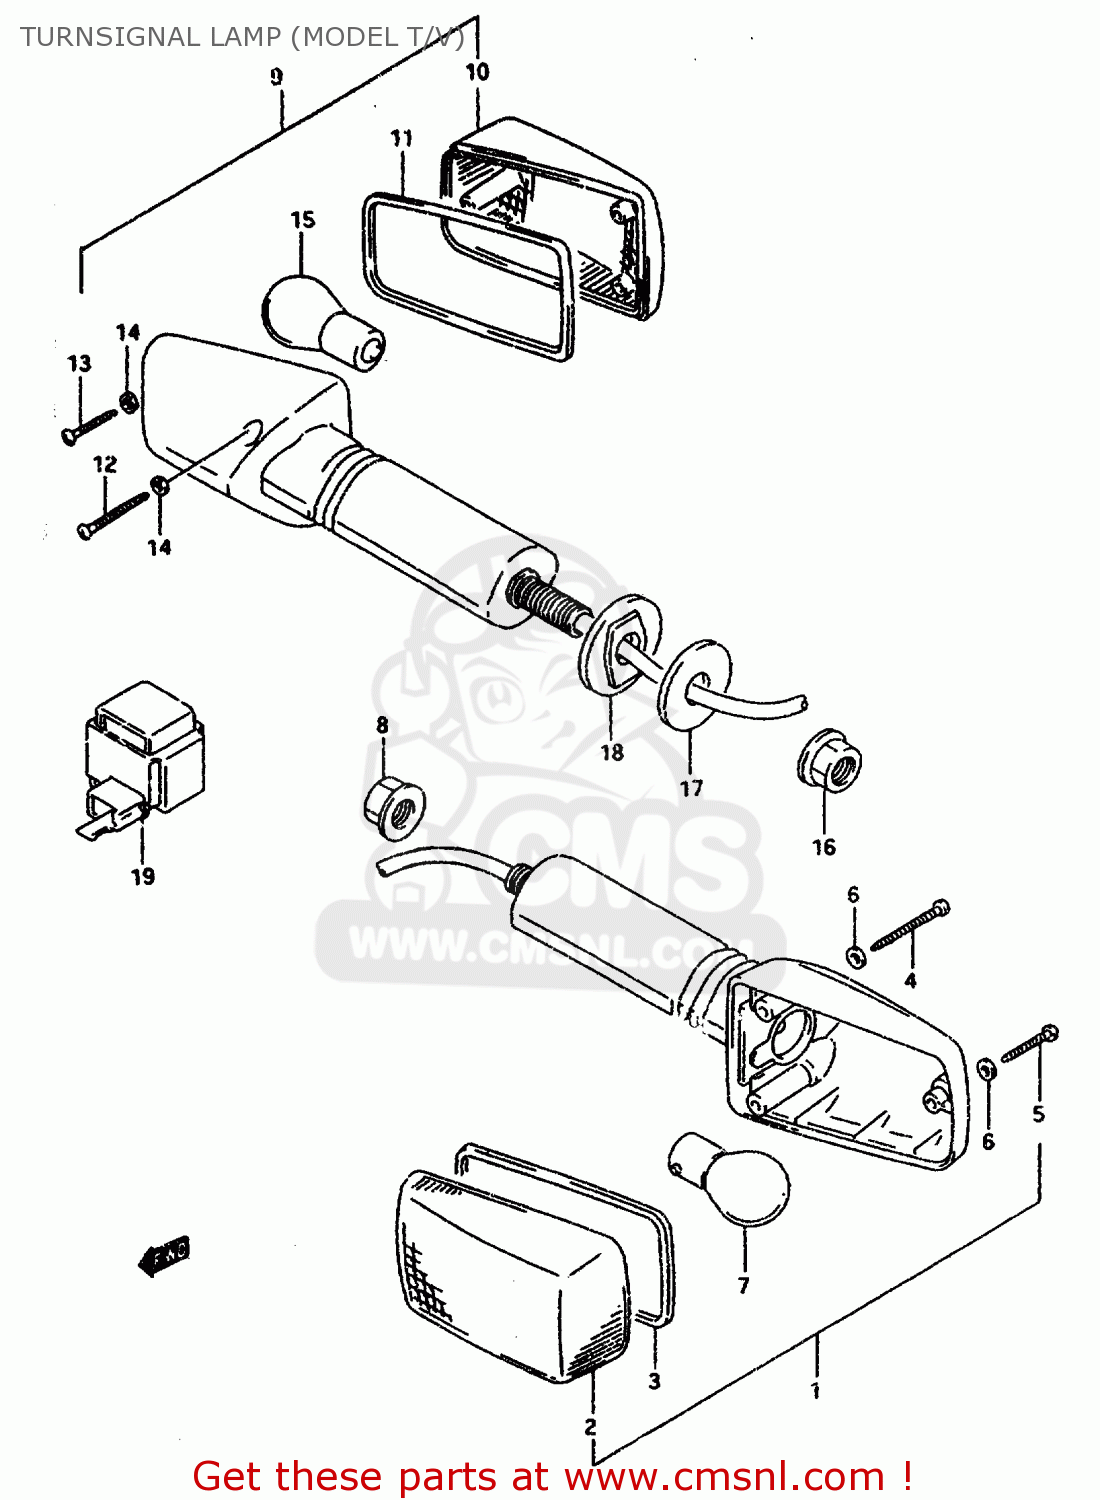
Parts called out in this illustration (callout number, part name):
1	LAMP ASSY,FR TURN SIGNAL
2	LENS
3	GASKET (NAS)
4	SCREW(3X30)
5	SCREW
6	GASKET (NAS)
7	BULB(12V21W)
8	NUT
9	LAMP ASSY,RR TURNSIGNAL
10	LENS
11	GASKET (NAS)
12	SCREW(3X30)
13	SCREW
14	GASKET (NAS)
15	BULB(12V21W)
16	NUT
17	WASHER(10.5X30X2.3)
18	SPACER,RR TURNSIGNAL
19	RELAY ASSY,TURNSIGNAL LAMP
20	RELAY ASSY,TURNSIGNAL LAMP
